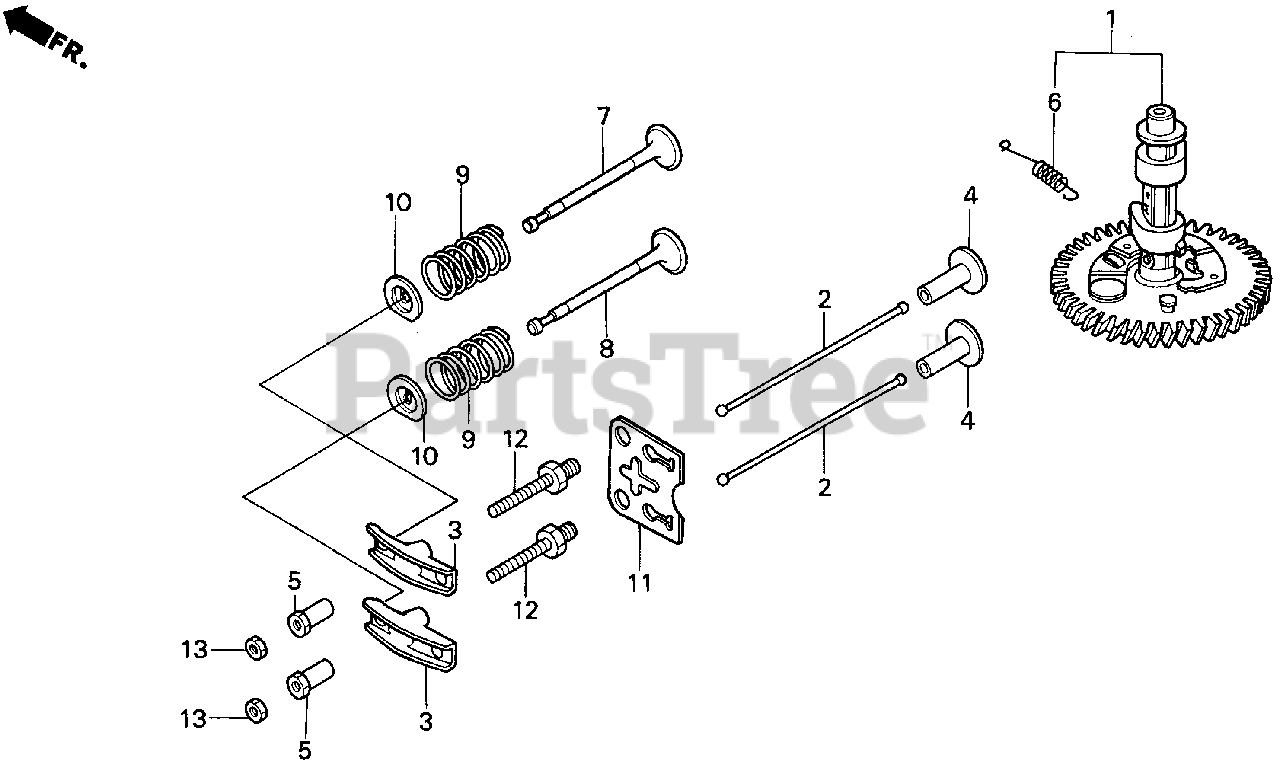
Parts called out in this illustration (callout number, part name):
1	CAMSHAFT ASSY.
2	ROD, PUSH
3	ARM, VALVE ROCKER
4	LIFTER, VALVE
5	PIVOT, ROCKER ARM
6	SPRING, WEIGHT RETURN
7	VALVE, IN.
8	VALVE, EX.
9	SPRING, VALVE
10	RETAINER, IN. VALVE SPRING
11	PLATE, PUSH ROD GUIDE
12	BOLT, PIVOT (8MM)
13	NUT, PIVOT ADJ.
